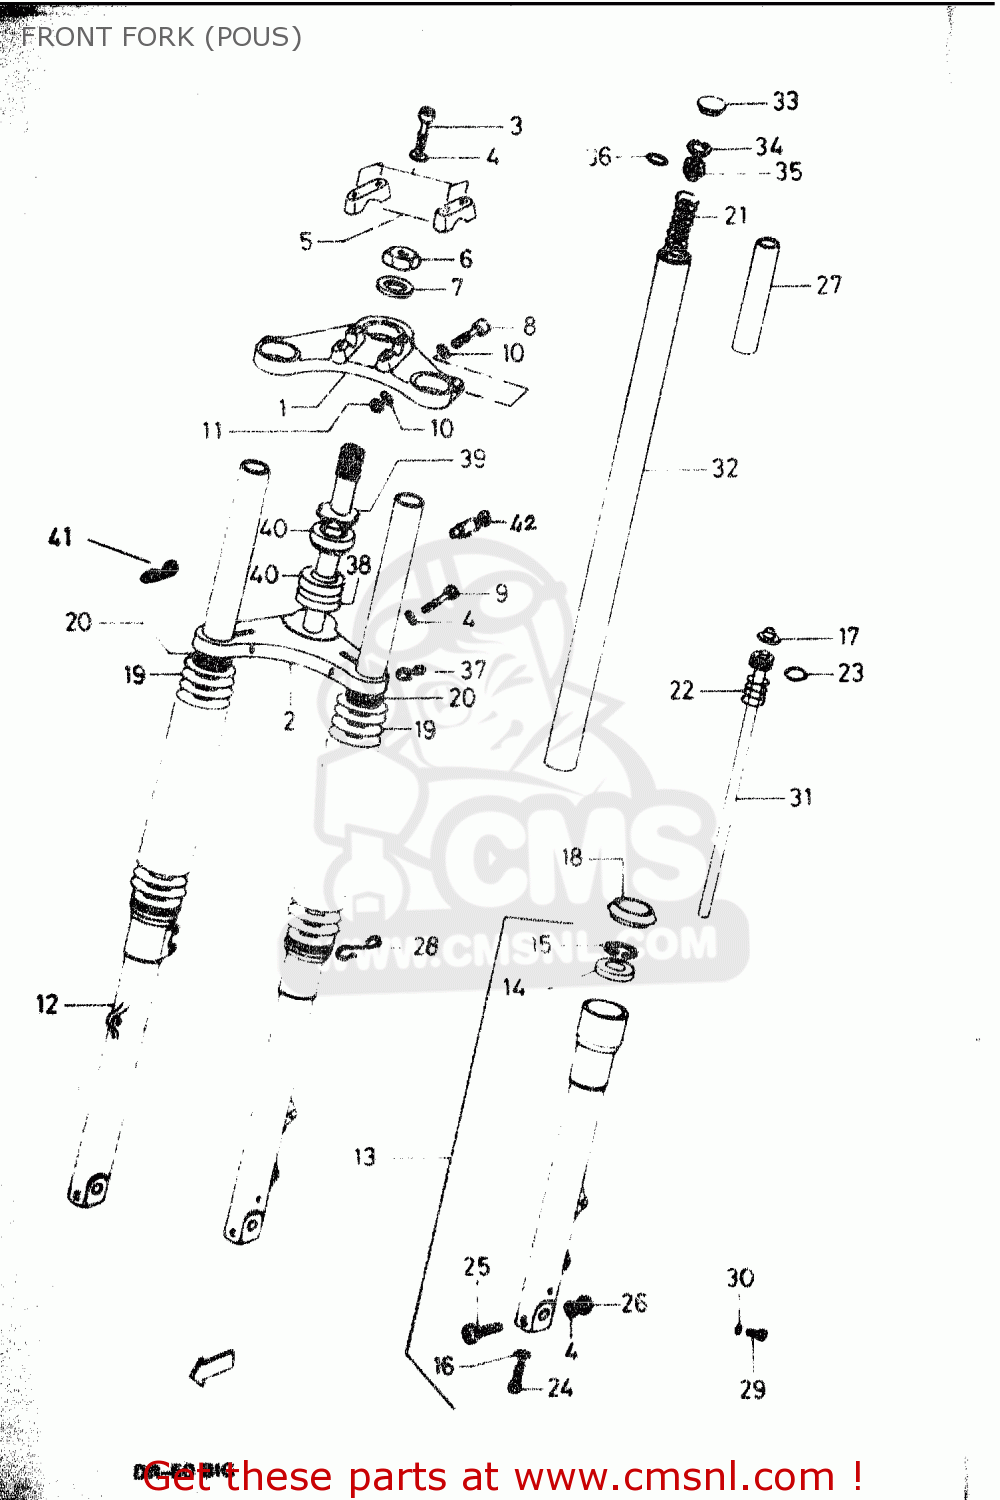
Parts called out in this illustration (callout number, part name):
1	EMBLEM SUZUKI
2	EMBLEM DR
3	EMBLEM BIG 50
4	EMBLEM COVER FUEL TANK UPPER RH
5	EMBLEM COVER FUEL TANK UPPER RL
6	EMBLEM COVER FUEL TANK LOWER RH
7	WASHER
8	EMBLEM DUAL SPORT
9	EMBLEM, COVER FRAME RH
10	EMBLEM, COVER FRAME RL
11	EMBLEM, COVER FUEL TANK LOWER REAR, RL
12	DAMPER ASSY, RH
13	EMBLEM, COVER FUEL TANK UPPER REAR, RL
14	EMBLEM, COVER FUEL TANK UPPER REAR, RH
15	SNAP RING SB 40
16	WASHER
17	BUSH
18	CAP
19	BOOT (BLUE)
20	BAND, BOOT UPPER
21	SPRING
22	SPRING
23	O RING
24	SCREW M8X20 DIN 912
25	SCREW M8X50 DIN 912
26	NUT
27	SPACER
28	GUIDE, LOWER
29	SCREW M4X6 DIN 84
30	O RING
31	CYLINDER ASSY
32	TUBE, INNER
33	CAP
34	SNAP RING JV 26
35	GUIDE SPRING
36	O RING
37	GUIDE, UPPER
38	RACE, STEERING OUTER LOWER
39	RACE, STEERING OUTER UPPER
40	RACE, STEERING INNER
41	GUIDE, SPEEDOMETER CABLE
42	LOCK SET, STEERING
